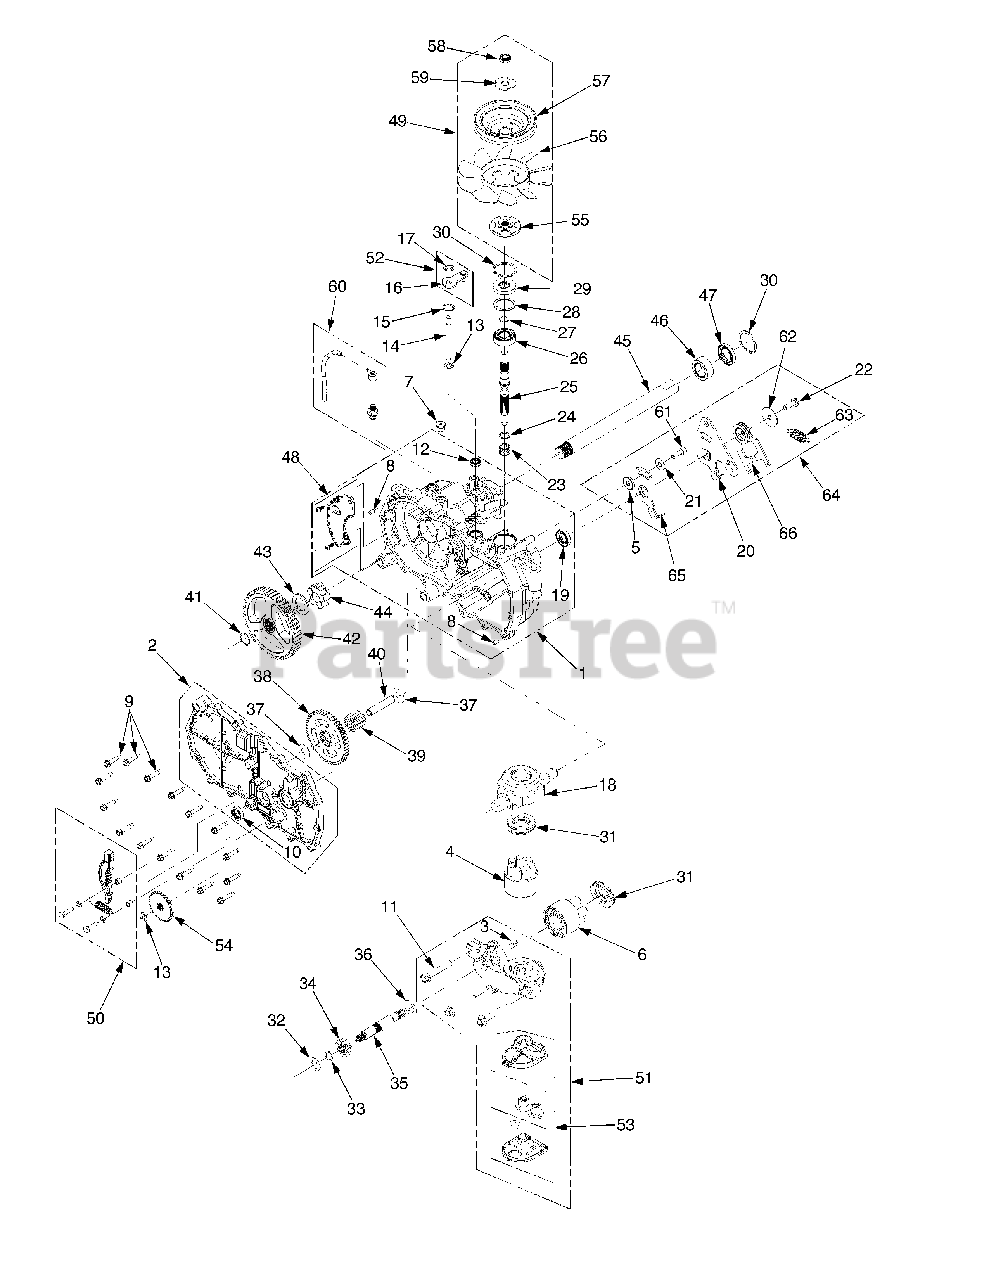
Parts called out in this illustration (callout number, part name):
1	Housing Ass’y, Main LH
2	Side Assembly LH
3	Plate, Bypass
4	Block Kit - 7 Piston
5	Spacer, .32 x 1.005 x .179
6	Block Assembly, Cylinder
7	Straight Thread Pipe
8	Std. Handle Pin
9	Hex Flange Screw
10	Oil Seal .625 x 1.0 x .25
11	Screw
12	Seal, Lip
13	Retaing Ring .375 Ext.
14	Rod, Bypass
15	Retaining Ring .75 Int.
16	Arm, Bypass
17	Retaining Ring
18	Swashplate, trunnion
19	Seal, Lip
20	Control Arm LH
21	Washer 7/16 x 7/8 x .060
22	Screw, 5/16-24 x 1.0
23	Block Washer
24	Block Thrust Washer
25	Input Shaft
26	Ball Bearing
27	Retaining Ring
28	Spacer
29	Lip Seal
30	Retaining Ring
31	Thrust Washer
32	Flat Washer 5/8 x 1.0 x .05
33	Retaining Ring
34	Gear, Pinion, 13T
35	Shaft, Motor
36	Motor Shaft Washer
37	Washer, HT
38	Gear, 10T/48T
39	Gear, 10T Jackshaft
40	Pin, Jackshaft
41	Retaining Ring
42	Gear, Bull, 52T
43	Washer, 1.018 x 1.57 x .105
44	Sleeve Bearing
45	Shaft, Axle, 1.0 x 11.7
46	Bearing, Sleeve
47	Seal, Lip
48	Plate Kit, Expansion
49	Kit, Fan Pulley
50	Kit, Brake Arm
51	Kit, Center section
52	Kit, Bypass Arm RH
53	Filter Assembly
54	Disc, Brake Cog
55	Hub, Pulley
56	Fan, 7" 10 Blade
57	Pulley, 4.5
58	Hex Ins. L-Nut 1/2-20
59	OD Slotted Washer
60	Breather Kit
61	Screw, Patch 5/16-24 x 1
62	Washer, .343 x 1.5 x .062
63	Extension Spring
64	Kit, Return Ass’y LH
65	Neutral Arm RH
66	Scissors Arm Kit
